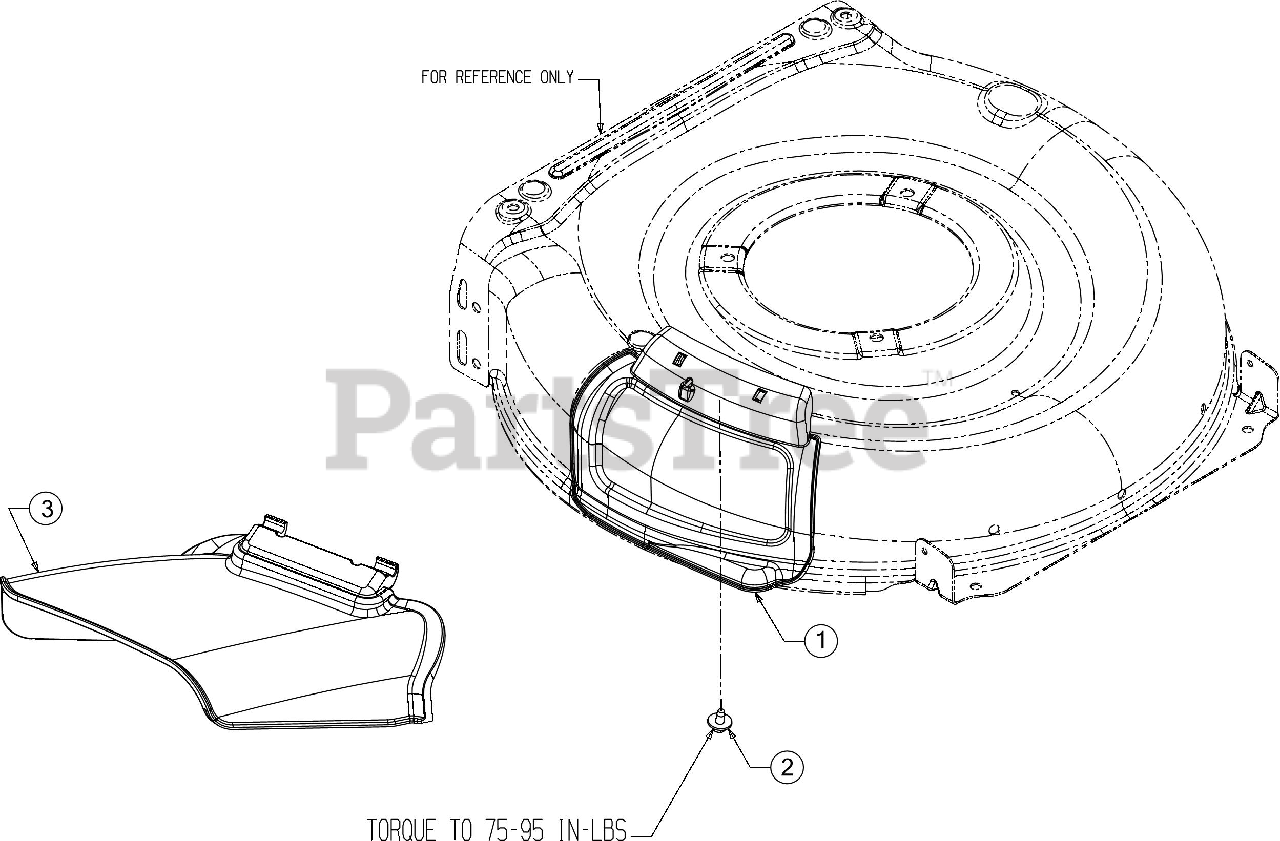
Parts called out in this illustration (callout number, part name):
1	HINGED MULCH PLUG ASSEMBLY
1	TORSION SPRING
1	HINGE PIN
1	CHUTE DEFLECTOR BRACKET
2	SCREW 1/4-20 x .50
3	SIDE DISCHARGE CHUTE
